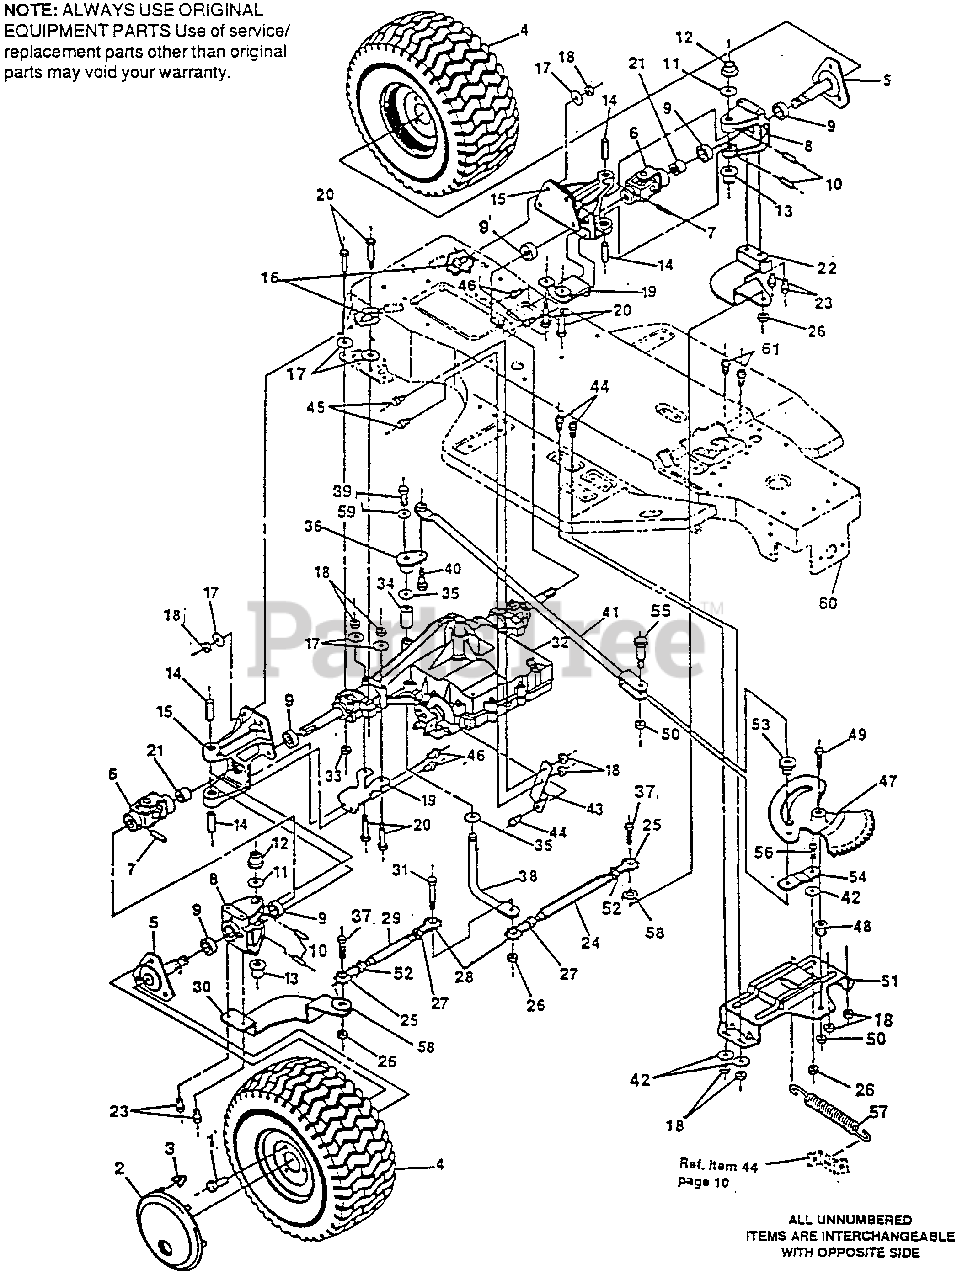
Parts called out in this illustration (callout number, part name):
1	Screw, Hx Hd, 1/2-20 x 1/2 In.
2	Hubcap, 8 In.
3	Clip, Hubcap
4	Wheel & Tire Assembly, Rear
4	Tire, 20x10.0x8, Turf
4	Valve Stem
5	Hub Assembly
6	U-Joint Assembly
7	Pin, Grooved, 1/4 x 1-1/2 In.
8	Bracket Assembly, Steering Pivot, Outer
10	Pin, Spring, 1/4 x 1-1/2 In.
11	Washer, Flat
12	Bushing, Shouldered
13	Bushing, Shouldered
14	Pin, Steering Hinge
15	Bracket Assembly, Steering Pivot, Inner
16	Screw, Hx Hd, 5/16-18 x 1 In.
17	Washer, Flat, 11/32 In.
18	Nut, Hx, Ctrlk 5/16-18 Thd.
19	Bracket, Transaxle Mounting
20	Screw, 5/16-18x2.50 Hhc Gr5.
22	Arm, Rear Wheel Steer, L.H.
23	Screw, 3/8-16x1.00 Wahhtap blk
24	Tie Rod, L.H. (1/2"x9-1/2")
25	Tie Rod End, L.H.
26	Nut, Hex, Ctrlk, 3/8-24 Thd.
27	Nut, Hex, Jam, 3/8-24 Thd.
28	Tie Rod End, R.H.
29	Tie Rod , 1/2 x 8" Long
30	Arm, Rear Wheel Steer, R.H.
31	Screw, Hx Hd, 3/8-24 x 1-3/4 In.
33	Nut, Hx, Wd Fl, Lk 5/16-18 Thd
35	Washer, Flat, 49/64 In.
36	Steering Pivot
37	Screw, 3/8-24 x 1-1/4 In.
38	Shaft, Steering Pivot
39	Screw, 5/16-24 x 1 In.
40	Bolt, Shoulder, 3/8-24 Thd.
41	Rod Assembly, Rear Wheel Steer
42	Washer, Flat, 3/8 In.
43	Bracket, Transaxle Stabilizer
44	Screw, Hx Hd, Self-Tap, 5/16-18 x 3/4 In.
45	Screw, 5/16-18x.63 Hhc Gr2
46	Screw, 5/16-18X.88 Wahhtap
47	Assembly, Sector Gear
48	Bushing, Sector Gear
49	Screw, Hx Hd, 1/2-20 x 2-3/8 In.
50	Nut, Hx, Ctrlk, 1/2-20 Thd
51	Plate, 4-Wheel Steer Pivot
52	Nut, Jam, 3/8-24 Thd.
53	Cam Yoke Roller
54	Arm, Roller Swing
55	Shoulder Bolt, Cam Roller
56	Shoulder Bolt, Cam Follower Arm Pivot
57	Spring, Clutch/Brake Pedal Return
58	Washer, Split Lock
59	Washer, Flat
60	Main Frame
61	Screw, 5/16-18 x 1/2 In. Taptite
